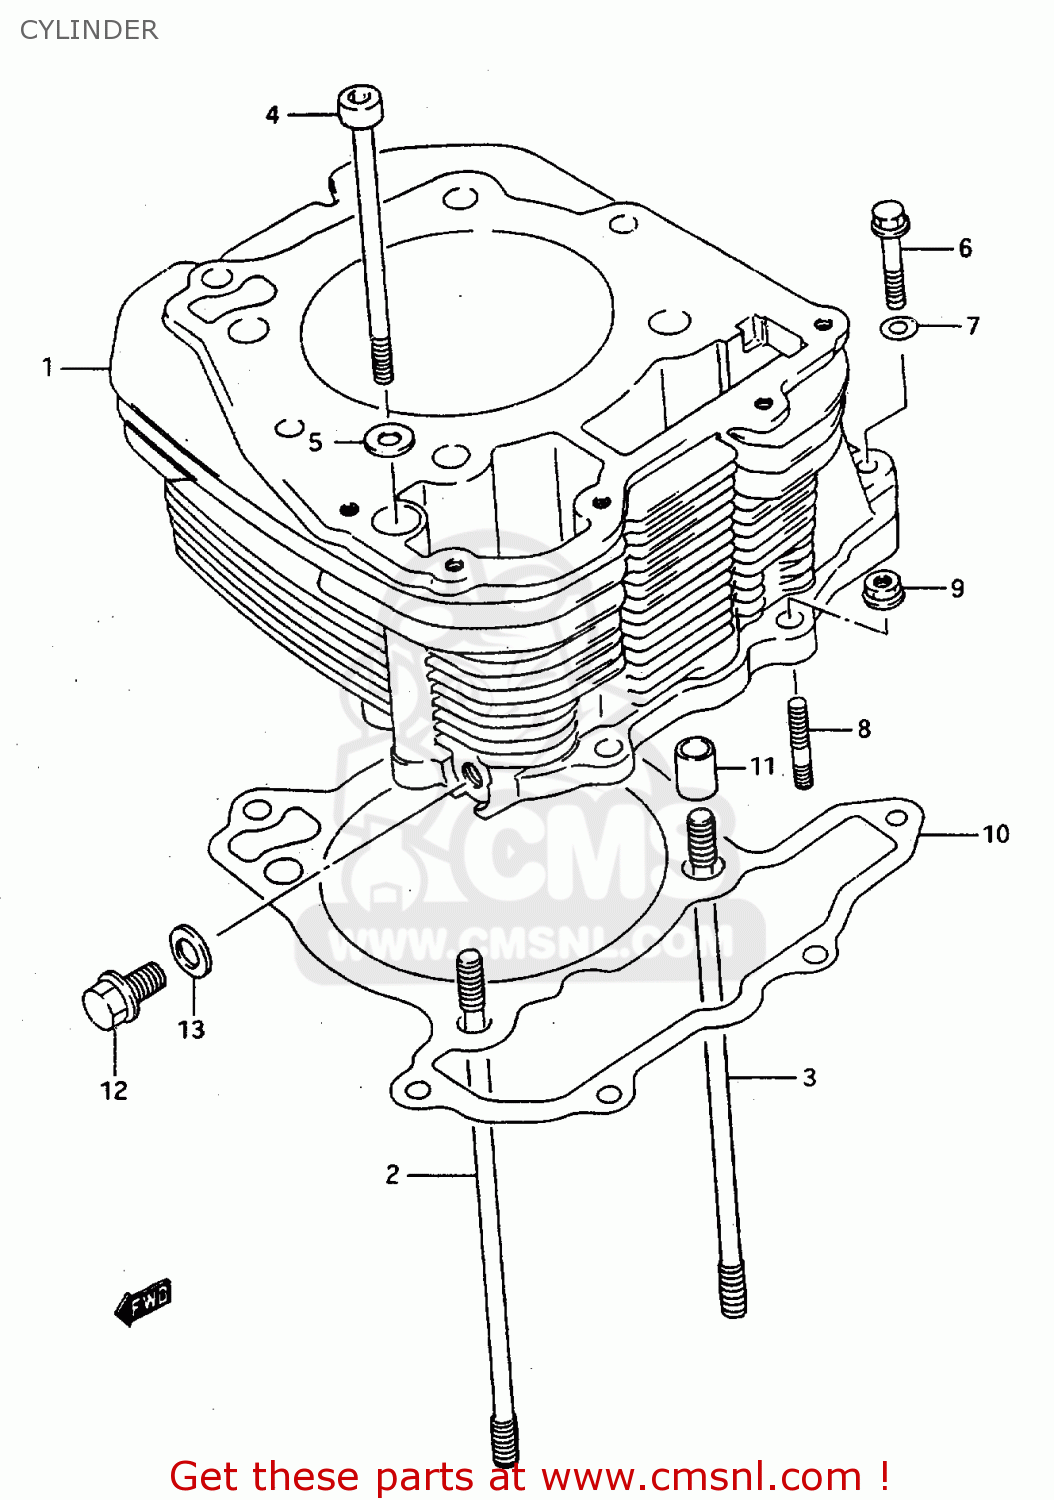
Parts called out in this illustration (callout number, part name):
1	CYLINDER
2	BOLT,STUD
3	BOLT,STUD(10X195)
4	BOLT L:115
5	GASKET(7.2X13X1.2) (NAS)
6	BOLT
7	GASKET(5.8X13X1.2) (NAS)
8	BOLT,STUD
9	NUT
10	GASKET,CYLINDER (NAS)
11	PIN
12	BOLT
13	GASKET(10.2X20X2).3 (NAS)
